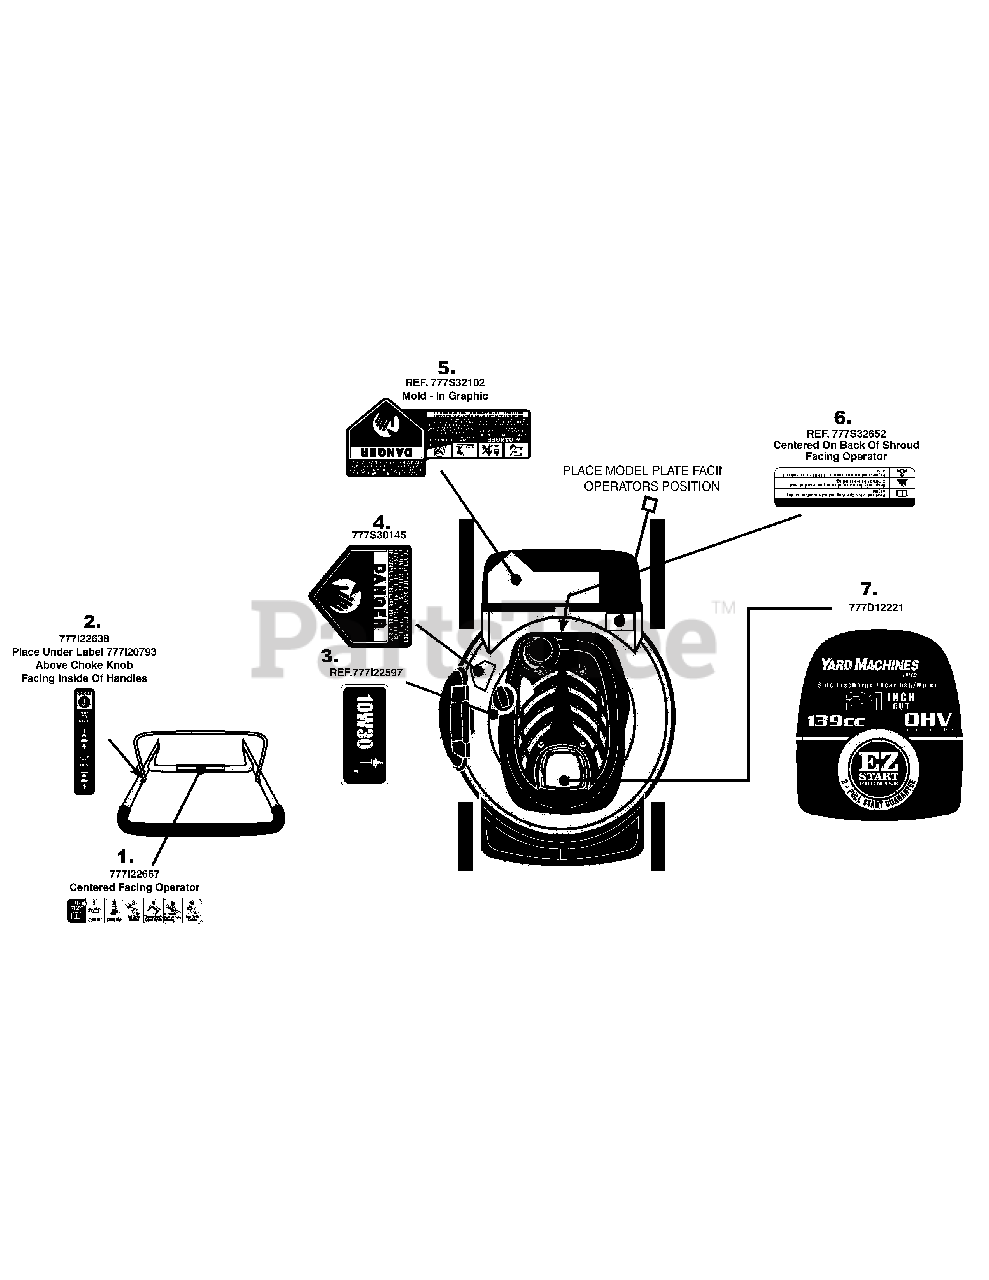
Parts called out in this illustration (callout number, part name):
1	LABEL-MOWER HANDLE
2	LABEL-MOWER HANDLE:CHOKE START/RUN
3	LABEL:MOWER SHROUD
4	LABEL
5	LABEL
6	LABEL:MOWER:ENGINE SHROUD
7	LABEL-MOWER SHROUD YM EZ START
